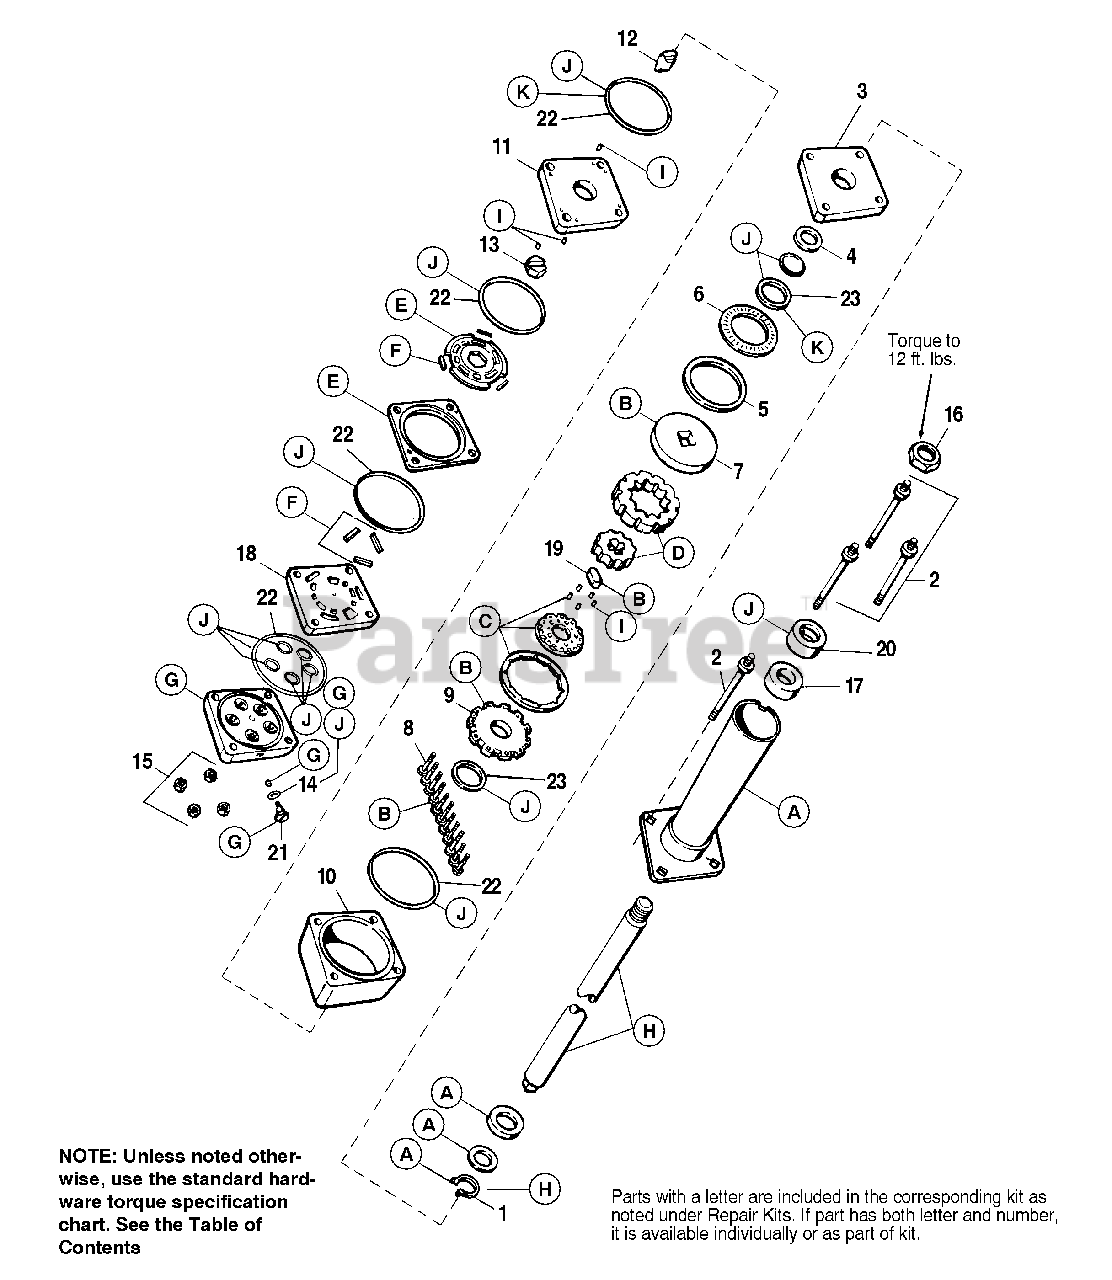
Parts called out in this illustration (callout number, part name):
1	RING, Retaining
2	BOLT
3	PLATE, Upper Cover
4	SPACER, Seal
6	BEARING, Thrust
7	PLATE, Drive
8	CAPSCREW, Hex Hd.
9	COVER, Commutator
10	RING, Metering
11	MANIFOLD, Isolation
12	LINK, Drive
13	DRIVE ASSY., Hex
14	"O" RING
15	LOCKNUT, Hex, 5/16-24
16	NUT, Hex, 5/8-18
18	MANIFOLD, Port
20	SEAL, Dust
21	PLUG
22	SEAL
23	SEAL
A	UPPER COVER ASSY. KIT
B	METERING ASSY. KIT
C	COMM. & RING ASSY. KIT
D	ROTOR ASSY. KIT
E	VALVE & RING KIT
F	SPRING KIT
G	PORT COVER & CHECK VALVE ASSY.
H	INPUT SHAFT ASSY. KIT
I	NEEDLE ROLLER KIT
J	SEAL KIT
K	SEAL KIT
